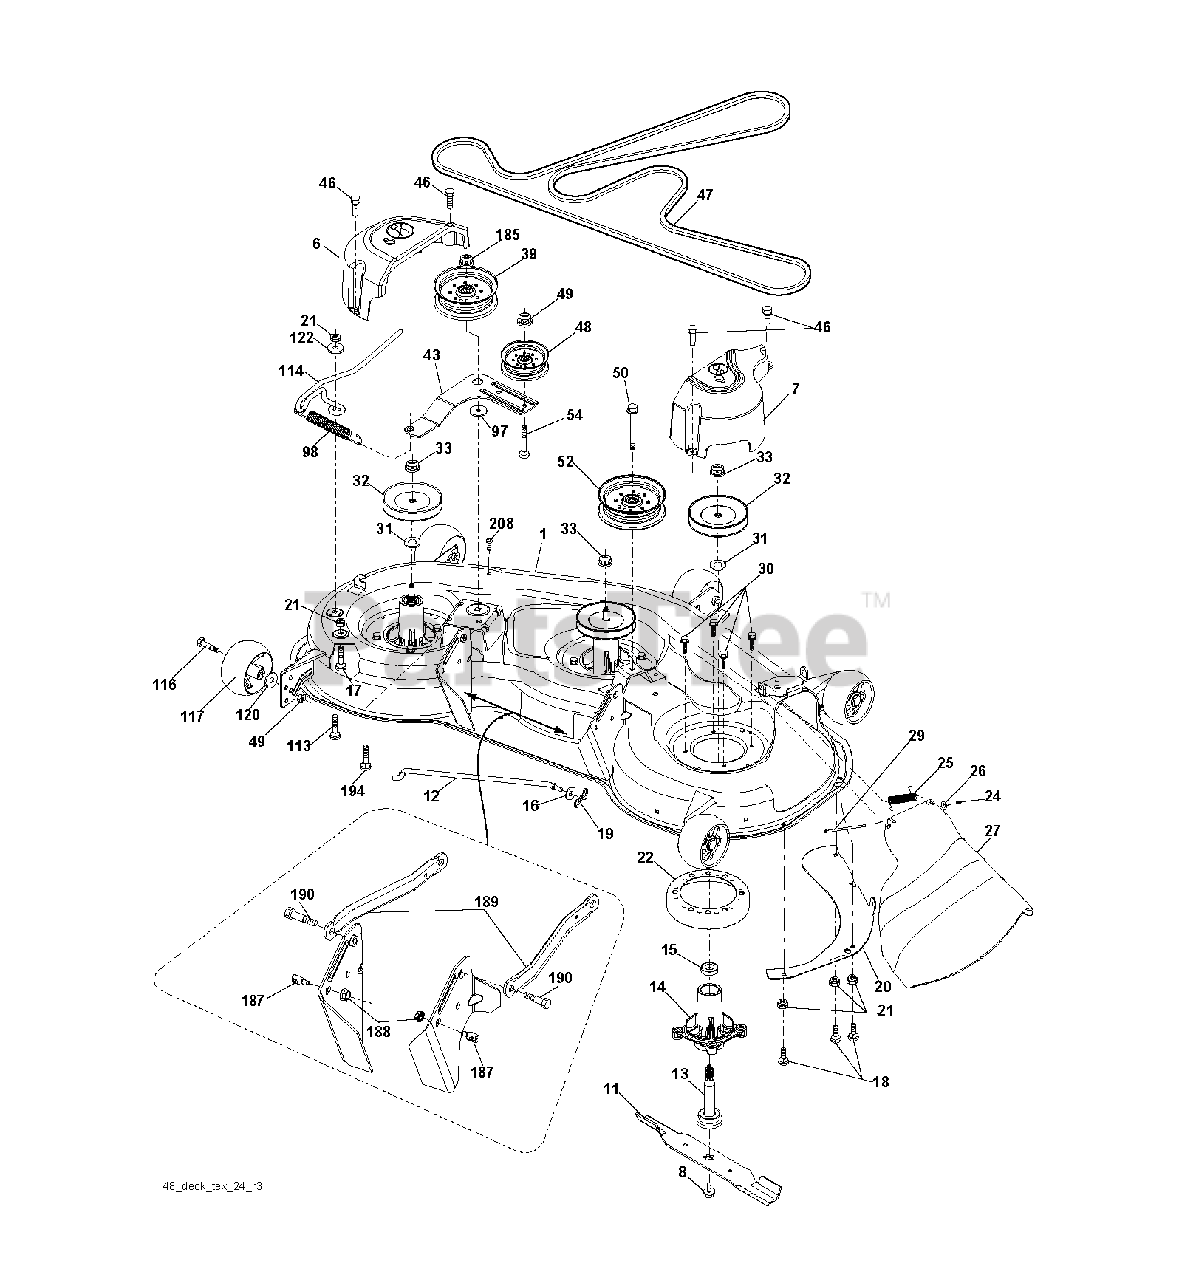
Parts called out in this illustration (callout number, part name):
1	DECK.WELDMENT.48"2006
6	COVER.MANDREL.LH.48"
7	COVER.MANDREL.RH.48"
8	BOLT 7/16 ASM BLADE
11	48" HI-LIFT BLADE
12	ROD.ANTI.SWAY.48/54"K4
13	SHAFT ASM MANDREL
14	HOUSING MANDREL
16	WASHER
17	BOLT
18	BOLT
19	PIN.COTTER.5/16.BOW TI
20	BAFFLE, VORTEX MWR
21	LOCKNUT
22	STRIPPER, MWR ROUND
24	CAP-SLEEVE LT
25	SPRING, TORSION
26	NUT PUSH M
27	DEFLECTOR SUBS TO 532 180655
29	ROD.HINGE
30	SCREW, WASHER HEAD
31	WASHER.SPACER.MANDREL
32	PULLEY MANDREL
33	NUT.FLANGE.LOCK.TOP
39	PULLEY.IDLER.4.50/HUB SPECIAL
43	ARM.IDLER
46	SCREW.1/4-20X5/8
47	BELT.DRIVE.DECK
48	PULLEY.IDLER.48"PRIMARY
49	NUT LOCK FLG 3/8-16 UNC
50	SCREW TT 3/8-16X2-1/4 UNC
52	PULLEY.IDLER.2006
54	BOLT.3/8-16X1.50
98	SPRING, DECK DRIVE
114	ROD.TENSION.RELIEF.TEX
116	BOLT.SHOULDER.3/8-16X3-5/8
117	WHEEL. GUAGE RALLY
122	BUSHING.RELIEF.TENSION
185	NUT.LOCK.FLANGE.7/16
187	STUD.FASTNER.W/ANTI-ROTATE
188	NUT LOCK HEX FLANGE 5/16-18
189	ARM.SUSPENSION.MOWER
190	BOLT.SHOULDER
194	BOLT.CARR.SQNK.7/16
208	SCREW 3/8-16X1/2
